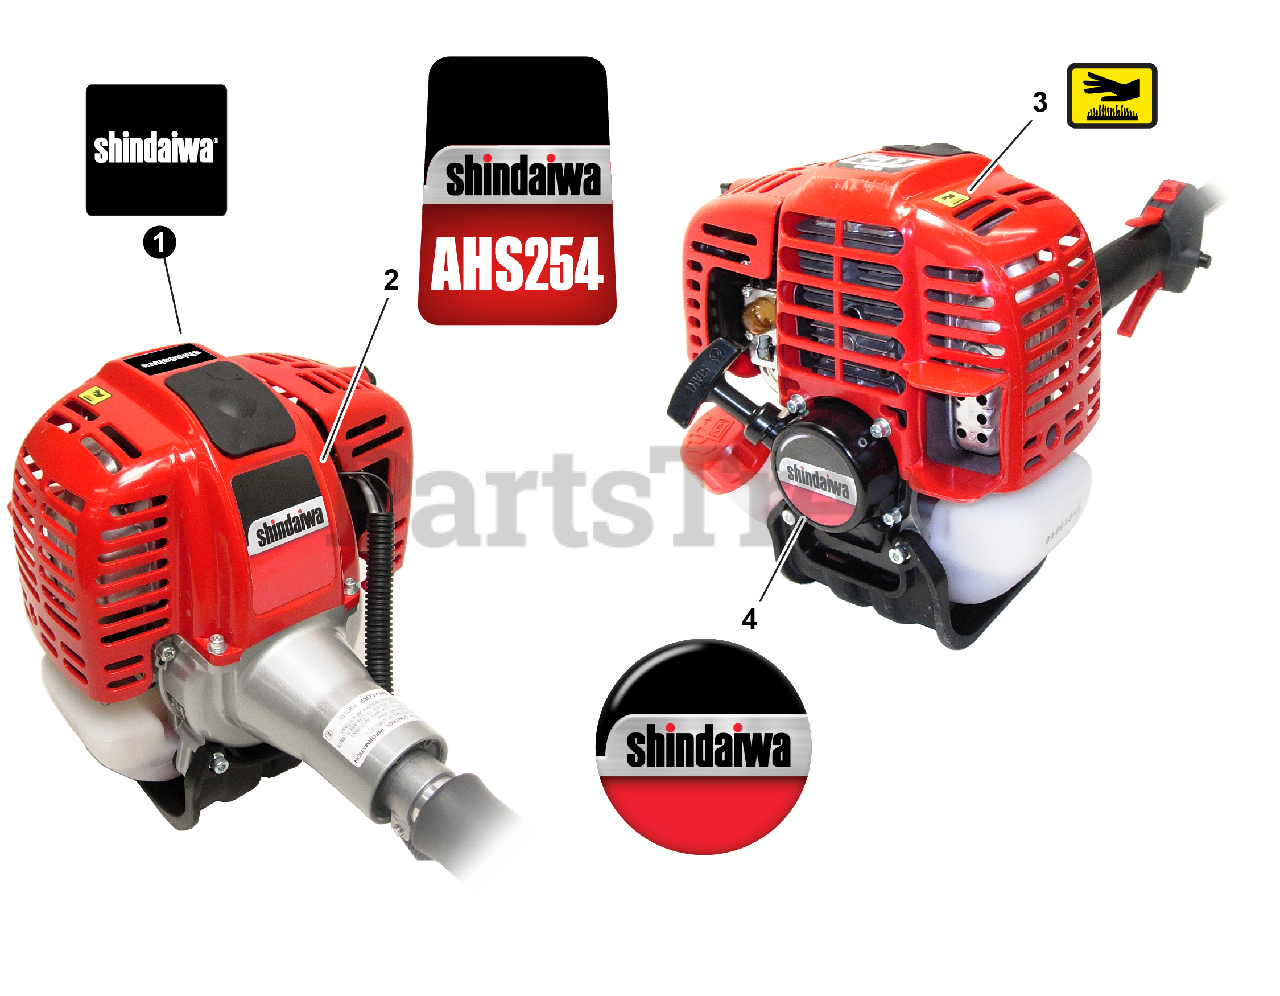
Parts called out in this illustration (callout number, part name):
1	LABEL, shindaiwa
2	LABEL, AHS254
3	LABEL, CAUTION - HOT
4	LABEL, RECOIL STARTER
